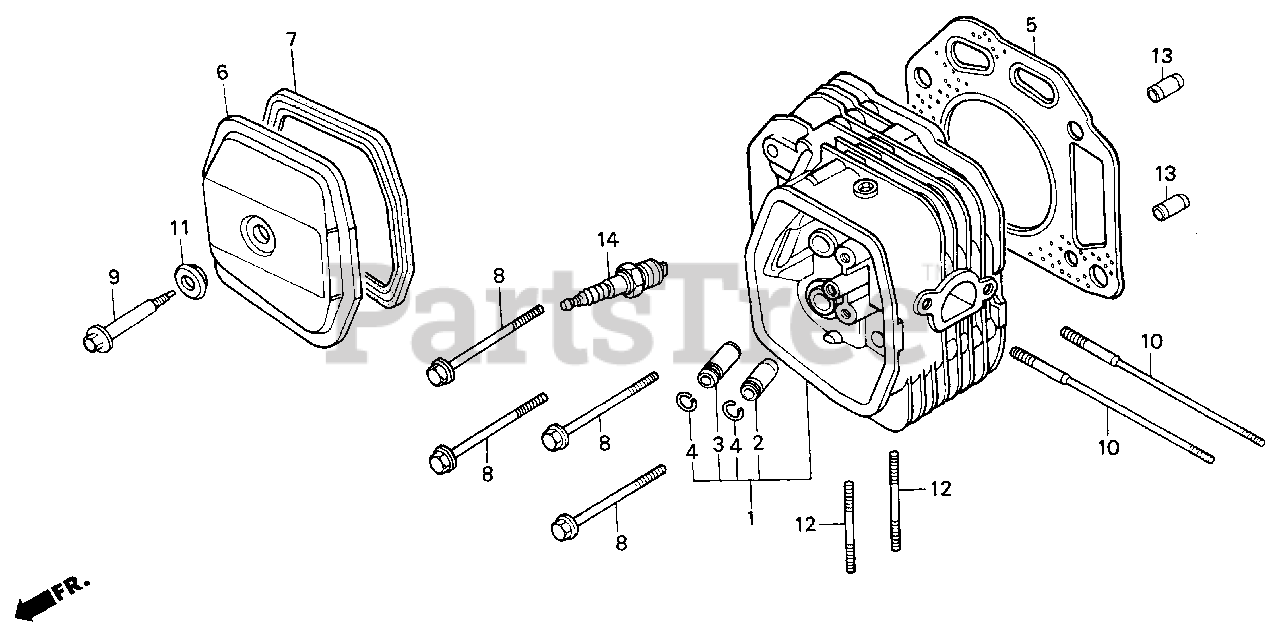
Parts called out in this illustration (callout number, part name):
1	CYLINDER HEAD
2	GUIDE, VALVE (OS)
3	GUIDE, EX. VALVE (OS)
4	CLIP, VALVE GUIDE
5	GASKET, CYLINDER HEAD
6	COVER, HEAD
7	GASKET, CYLINDER HEAD COVER
8	BOLT, FLANGE (10X85)
9	BOLT, HEAD COVER
10	BOLT, STUD (8X145)
11	WASHER, HEAD COVER
12	BOLT, STUD (8X22)
13	PIN A, DOWEL (12X20)
14	SPARK PLUG (BPR5ES) (NGK)
14	SPARK PLUG (W16EPR-U) (DENSO)
